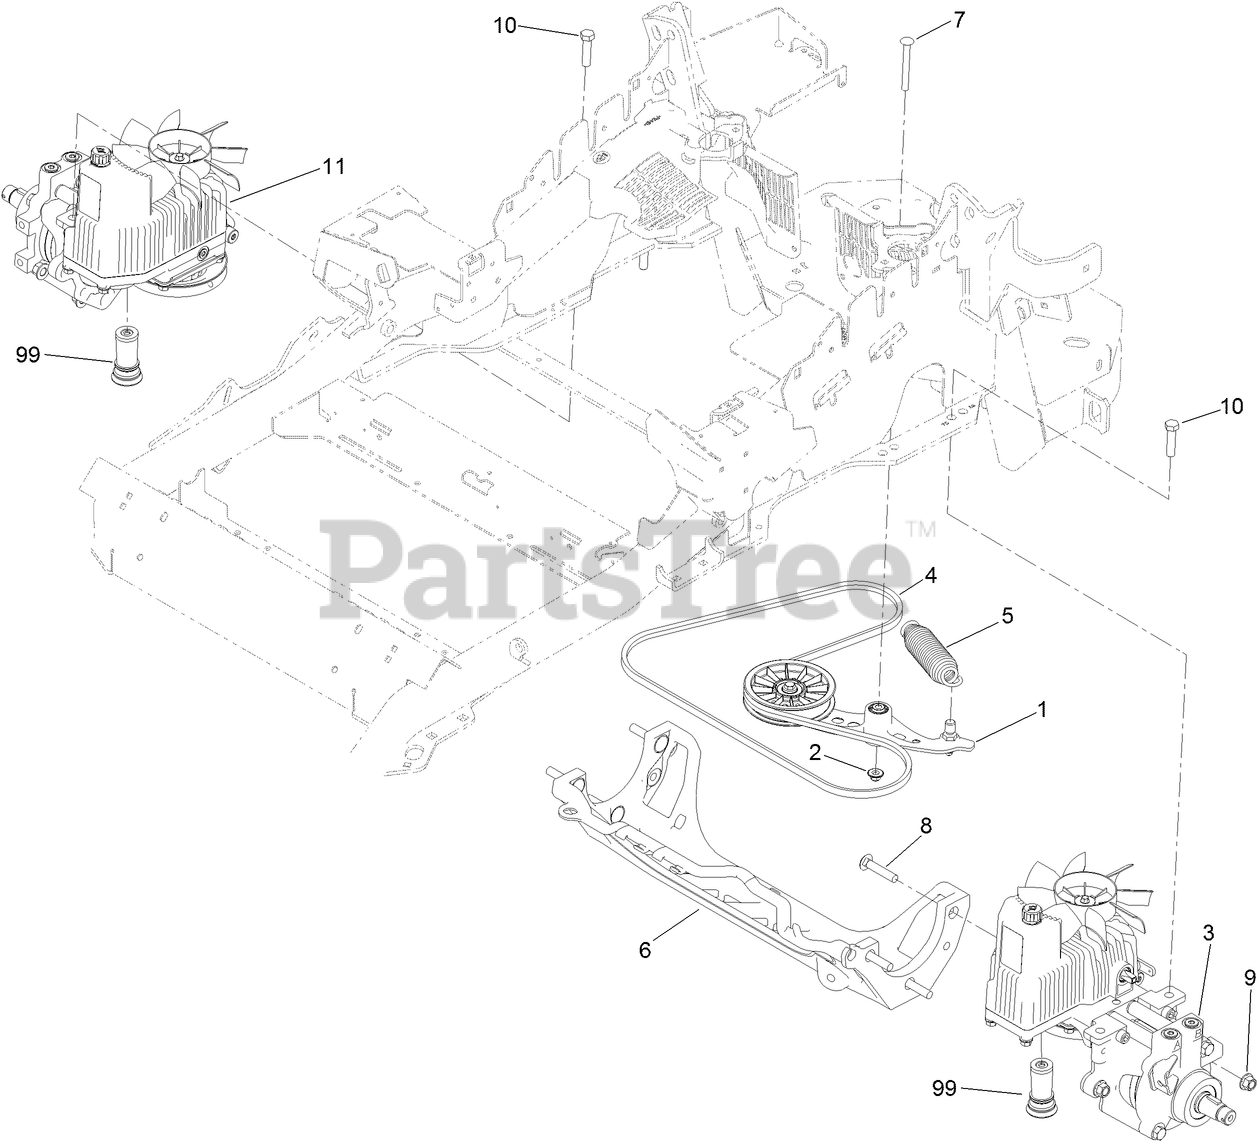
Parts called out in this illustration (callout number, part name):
1	PUMP IDLER ASM
2	NUT-FLANGE, NI
3	LH HYDRO ASM (12CC W/ SHOCK)
4	BELT
5	SPRING-EXTENSION
6	CRADLE-HYDRO
7	BOLT-SHOULDER, CARRIAGE
8	SCREW-CARR
9	NUT-LOCK
10	SCREW-HH
11	RH HYDRO ASM (12CC W/ SHOCK)
99	FILTER-HYDRO
